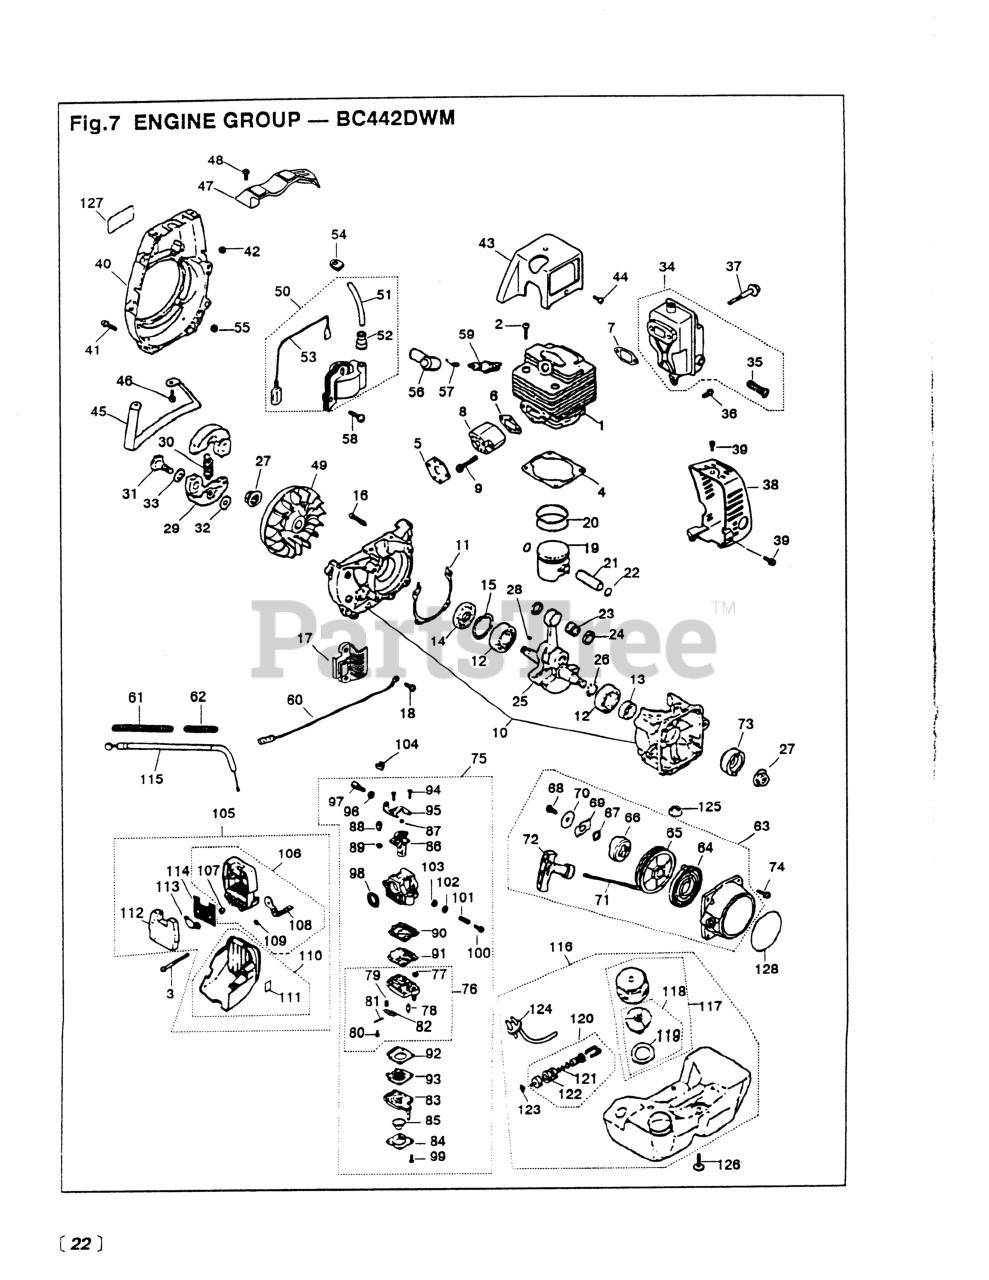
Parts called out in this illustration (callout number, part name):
8	INSULATOR (RPLS -13162)
10	CRANKCASE COMPLETE
13	SEAL, OIL - STARTER SIDE
15	RING, SNAP, M35 X 1.5
16	BOLT, M5 X 30
18	SCREW,M5 X 14 (RPLS 1400-15510
19	PISTON (NLA)
20	RING, PISTON (RPLS -41210)
21	PIN, PISTON
22	RING, SNAP
23	BEARING
24	WASHER (RPLS 1491-41510)
25	SHAFT (RPLS -42001)
26	SHIM (REPLACES 848-870-G000)
27	NUT, M10
28	KEY
31	SCREW
32	WASHER
33	WASHER (USE -51241)
35	ARRESTER
36	SCREW, M5 X 12
37	BOLT
38	COVER
39	SCREW, M5 X 12
40	COVER, FAN (REPLACES -31111)
43	COVER (RPLS -32110)
44	SCREW, M5 X 12
45	STAND
46	BOLT (REPLACES 01252-30514)
48	SCREW, M5X20 (RPLS.1400-75510)
50	COIL ASSEMBLY
52	CAP
54	GROMMET
57	SPRING
62	TUBE (RPLS -72930)
64	SPRING (RPLS -75220)
66	DOG
67	WASHER
68	SCREW
69	RETAINER (RPLS 1861-75161)
70	WASHER
71	ROPE
72	KNOB
73	PULLEY (RPLS -75210)
74	SCREW (USE 0263-90520 )
75	CARBURETOR (RPLS -81001)
76	BODY, PUMP
78	VALVE, INLET
79	SPRING, METERING LEVER
80	SCREW, METERING LEVER PIN
81	PIN, METERING LEVER
82	LEVER
83	BODY, PURGE
84	COVER, PUMP
85	PUMP, PRIMING
86	VALVE ASSEMBLY
88	SWIVEL
89	RING
90	GASKET, PUMP
91	DIAPHRAGM
92	GASKET, DIAPHRAGM
93	DIAPHRAGM (USE 4810-81260)
94	SCREW
96	NUT, CABLE ADJUSTER
97	SCREW, CABLE
98	RING, PACKING
99	SCREW
104	CAP, CABLE END
107	SLEEVE
110	COVER, AIR FILTER (RPLS -82201
111	LABEL
113	PLATE
115	CABLE COMPLETE
118	VALVE COMPLETE
119	PACKING (RPLS -85321)
120	FILTER ASSY
123	CLIP (REPLACES 2841-31280)
124	PIPE ASSY (RPLS -85800)
126	SCREW
128	LABEL, RECOIL(RPLS 1403-75411)
